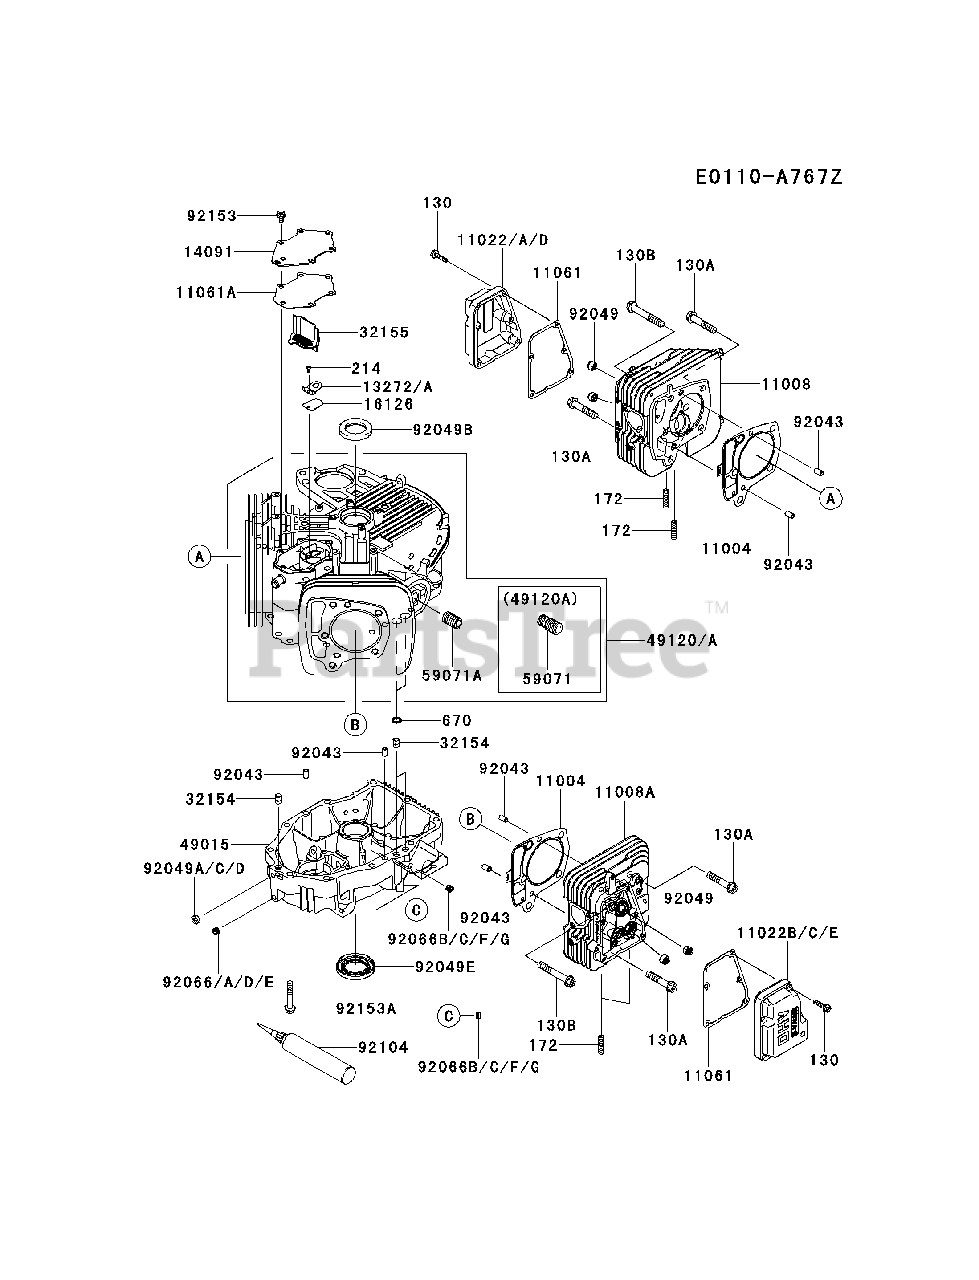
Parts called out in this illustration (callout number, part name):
130	BOLT-FLANGED,6X25
130A	BOLT-FLANGED,10X50
130B	BOLT-FLANGED,10X65
172	BOLT-STUD,8X18
214	SCREW-PAN+-,4X8
670	O RING,11MM
